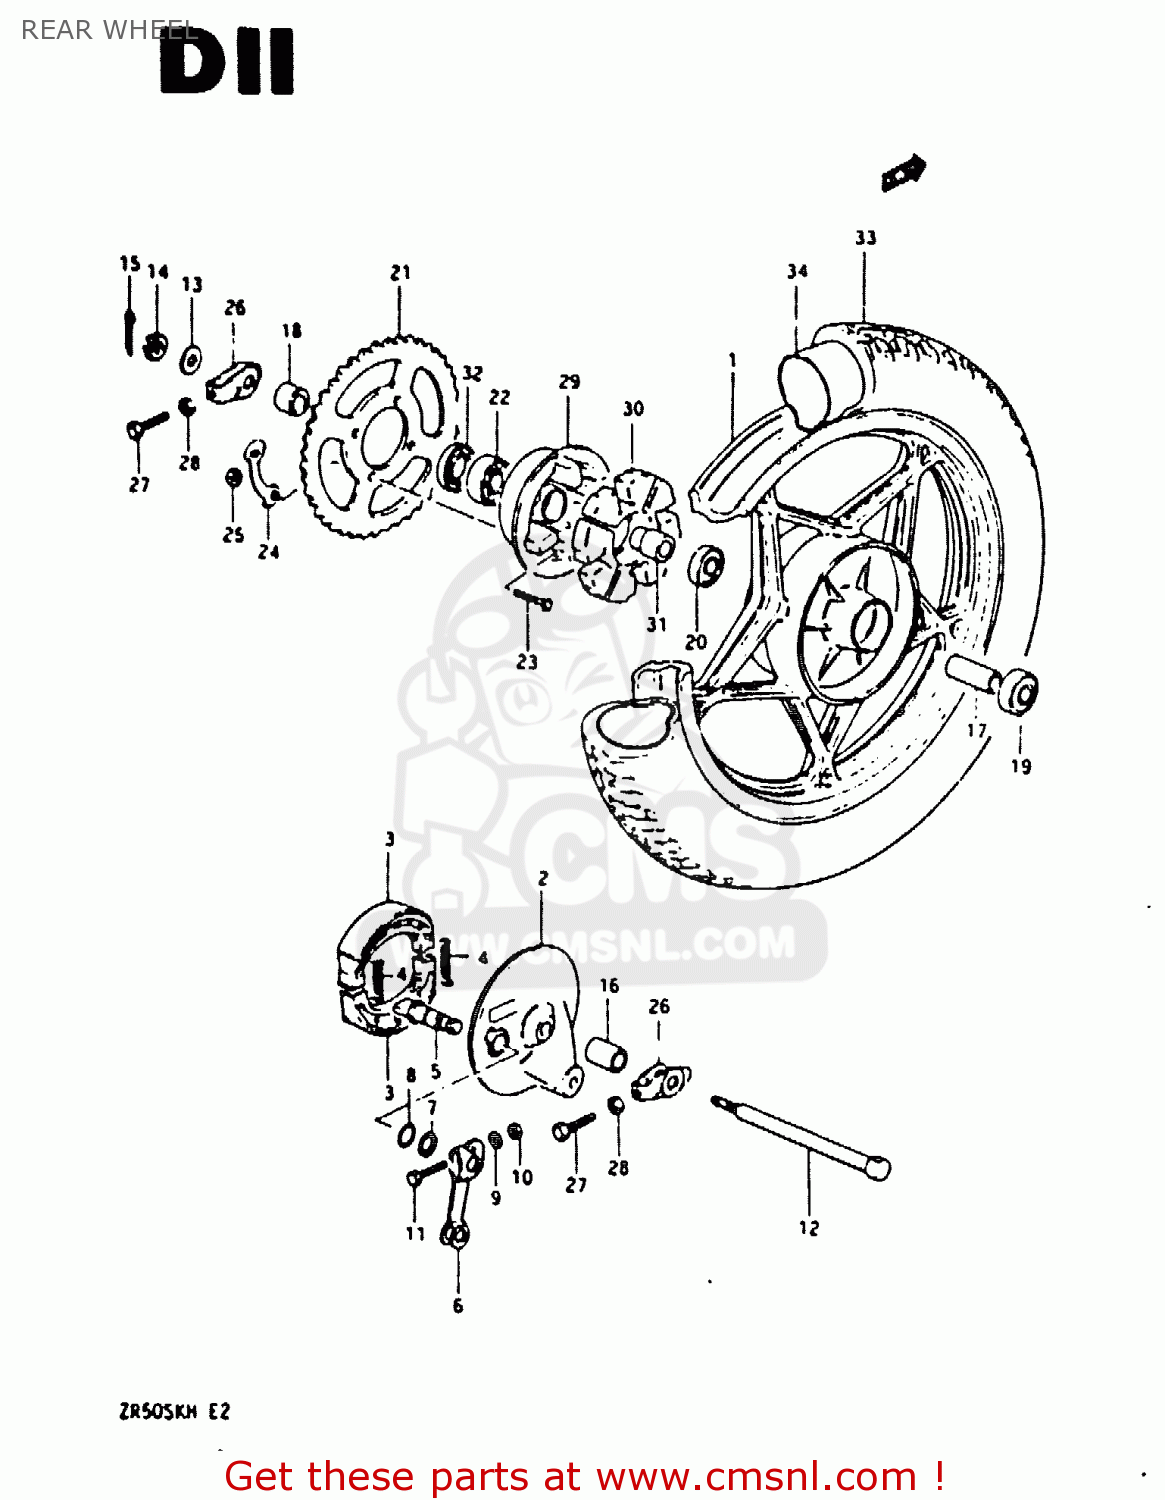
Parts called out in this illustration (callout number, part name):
1	WHEEL, REAR (160*18) (GOLD)
2	PANEL, REAR BRAKE ANCHOR
3	SHOE,BRAKE
4	SPRING(L:34)
5	CAM,FRONT BRAKE
6	LEVER,RR BRAKE CAM
7	WASHER (14.5X22X1.6)
8	O-RING (D:2.4 ID:13.8)
9	WASHER
10	NUT
11	BOLT(6X33)
12	AXLE,FRONT
13	WASHER
14	NUT 12MM
15	COTTER PIN
16	SPACER, AXLE RH
17	SPACER (12.6X19X58)
18	SPACER 12X25X2
19	BEARING
20	BEARING
21	SPROCKET,RR NT
22	BEARING(17X40X12)
23	BOLT(8X33.5)
24	WASHER
25	NUT
26	27
27	BOLT(6X38)
28	NUT
29	DRUM,REAR SPROCKET MOUNT
30	ABSORBER,RR HUB SHOCK
31	RETAINER,RR SPROCKET DRUM
32	SEAL OIL(25X40X6)
33	TIRE 2.75-18 070-458MM
34	TUBE,INNER
